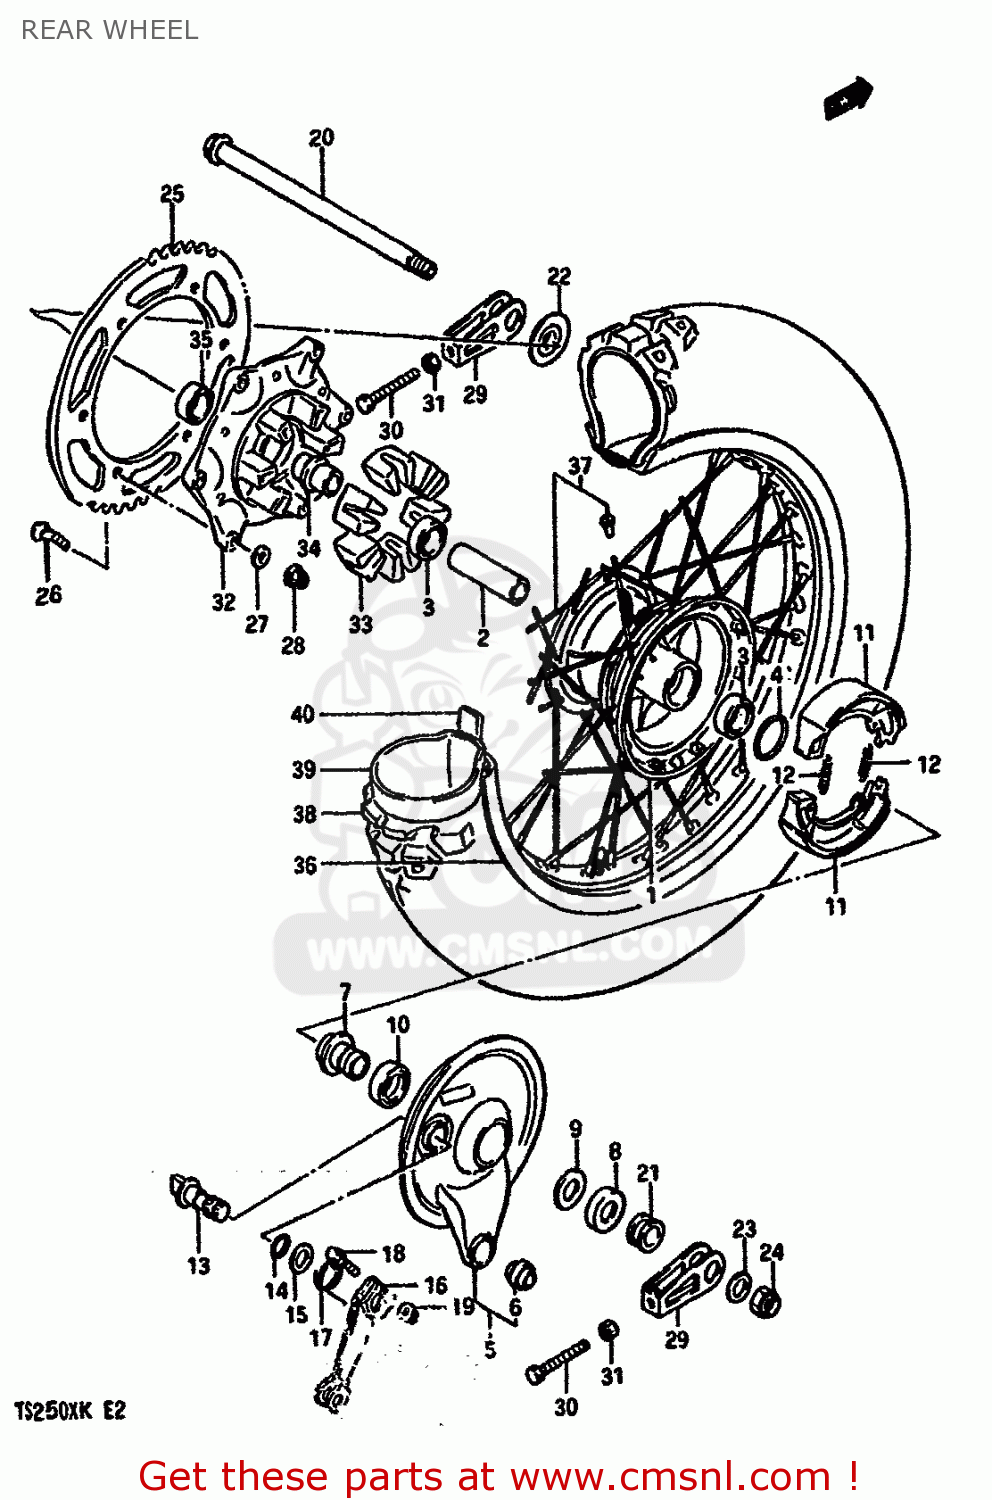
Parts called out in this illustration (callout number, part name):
1	HUB,REAR
2	SPACER,BEARING
3	BEARING
4	O RING(D:2.6,ID:39.7)
5	PANEL SET,REAR
6	BEARING
7	SPACER
8	CVR,RR BRAKE AHR PNL DUST SEAL
9	WASHER,THRUST
10	SEAL,OIL(20X27X5)
11	SHOE,BRAKE
12	SPRING(L:34)
13	CAM,BRAKE
14	O-RING
15	WASHER
16	LEVER,CAM
17	SPRING
18	BOLT 6X35
19	NUT
20	AXLE,REAR
21	SPACER,RH
22	SPACER,LH
23	WASHER
24	NUT 14MM
25	SPROCKET,REAR (NT:47)
26	BOLT(8X30.5)
27	WASHER
28	NUT
29	ADJUSTER,CHAIN
30	BOLT(8X47)
31	NUT
32	DRUM
33	ABSORBER,RR HUB SHOCK
34	RETAINER
35	BEARING
36	RIM,REAR WHEEL (2.15X17AL)
37	SPOKE SET
38	TIRE,REAR (130/80-17)
39	TUBE ASSEMBLY,WHEEL,INNER
40	PROTECTOR,WHEEL,INNER
